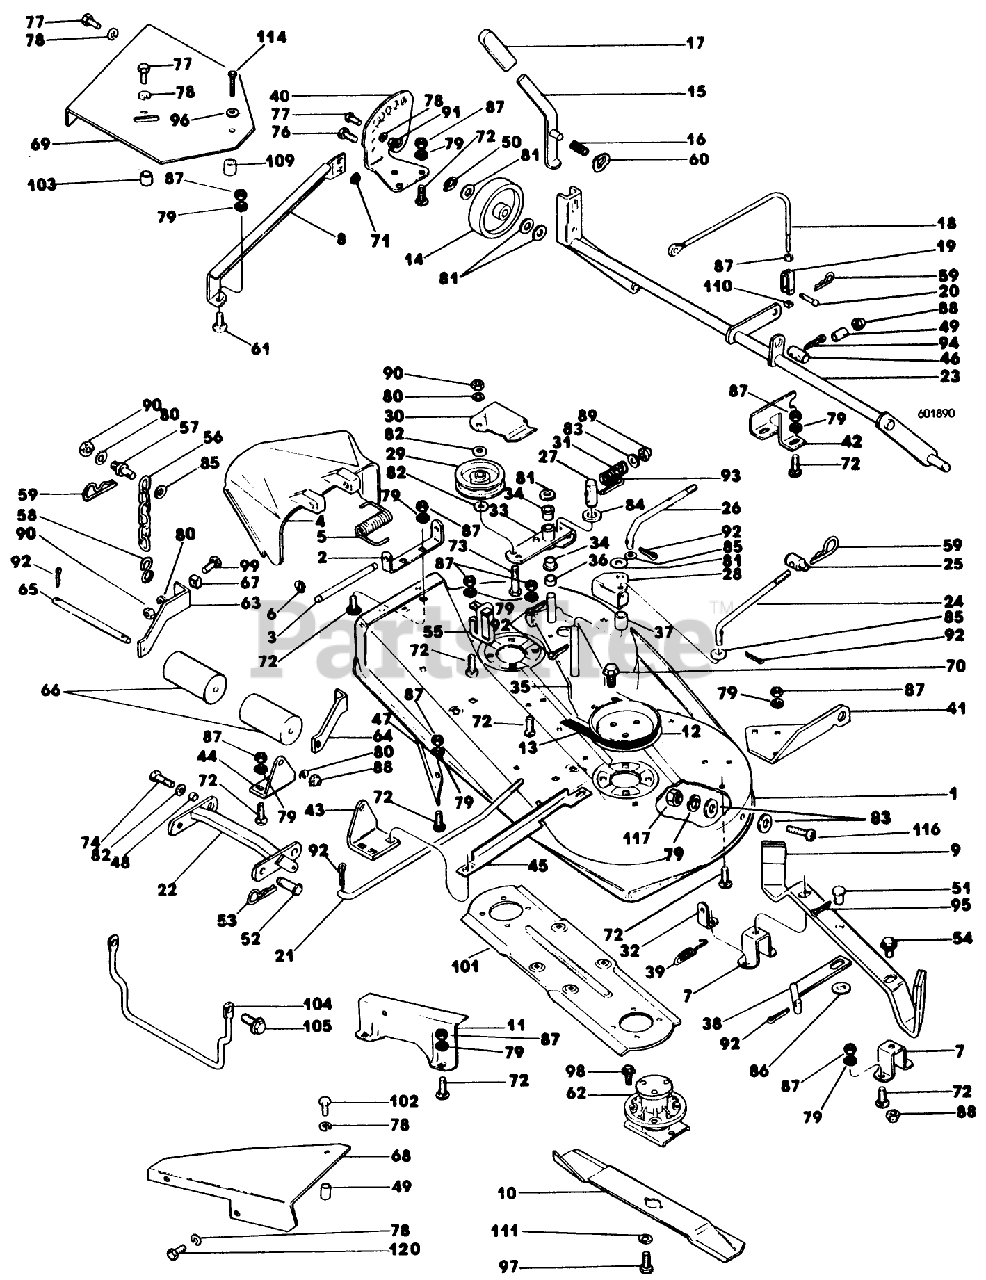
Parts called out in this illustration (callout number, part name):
49	Spacer
56	Lift Chain
62	Spindle Assembly
69	Belt Cover-R.H.
79	Lock Washer 5/16 Plated
